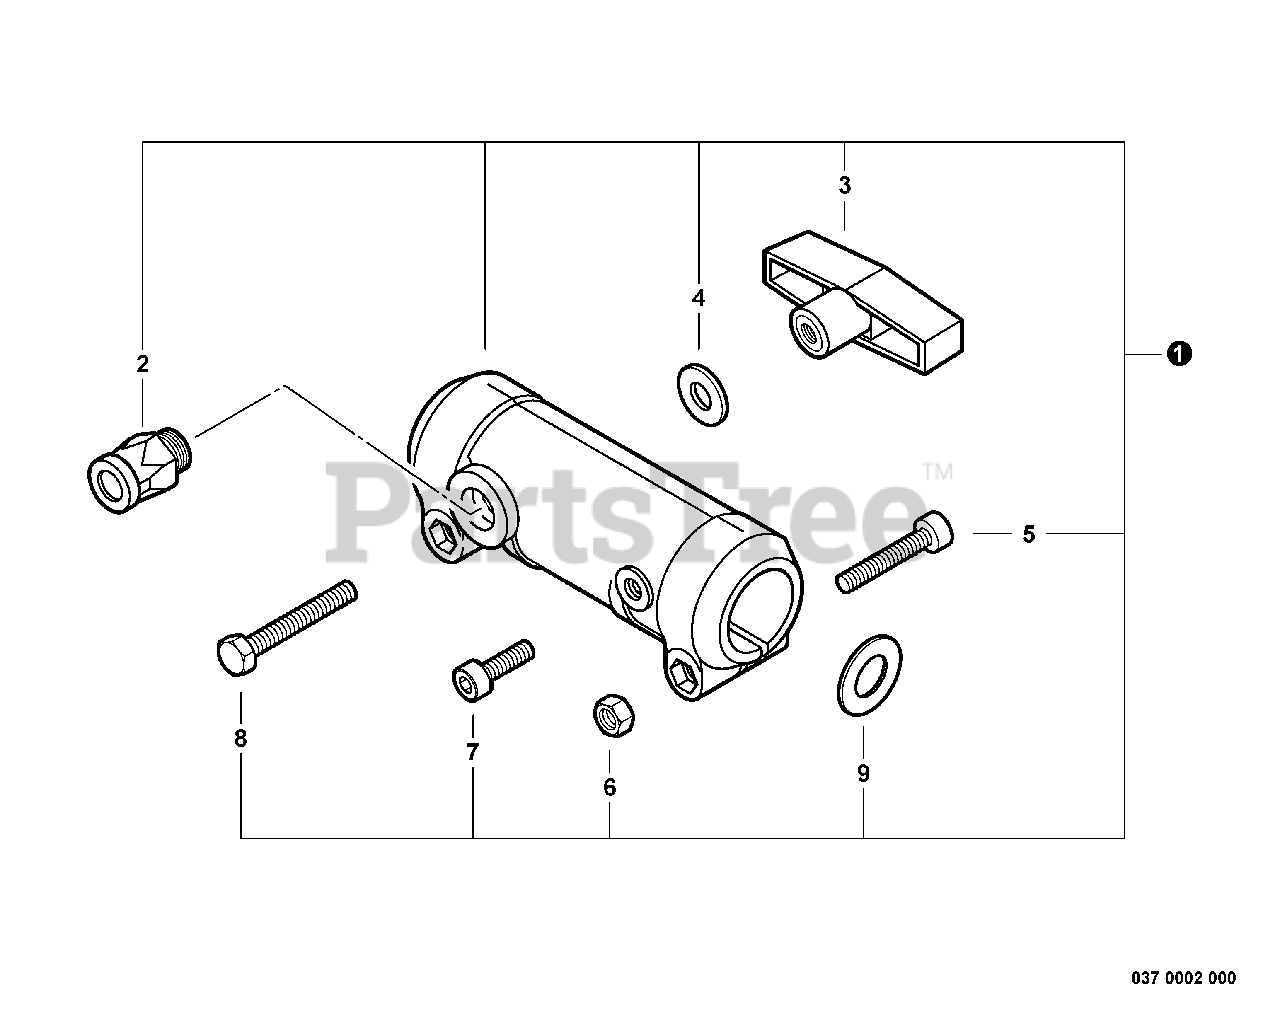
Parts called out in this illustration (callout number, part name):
1	COUPLER ASSY
2	LATCH ASSY
3	KNOB, FASTENER
4	WASHER 6.6×20×1.6
5	BOLT, TORX 6×25
7	BOLT, TORX 5×10
8	BOLT 6×40
9	WASHER 18 SPR STEEL
